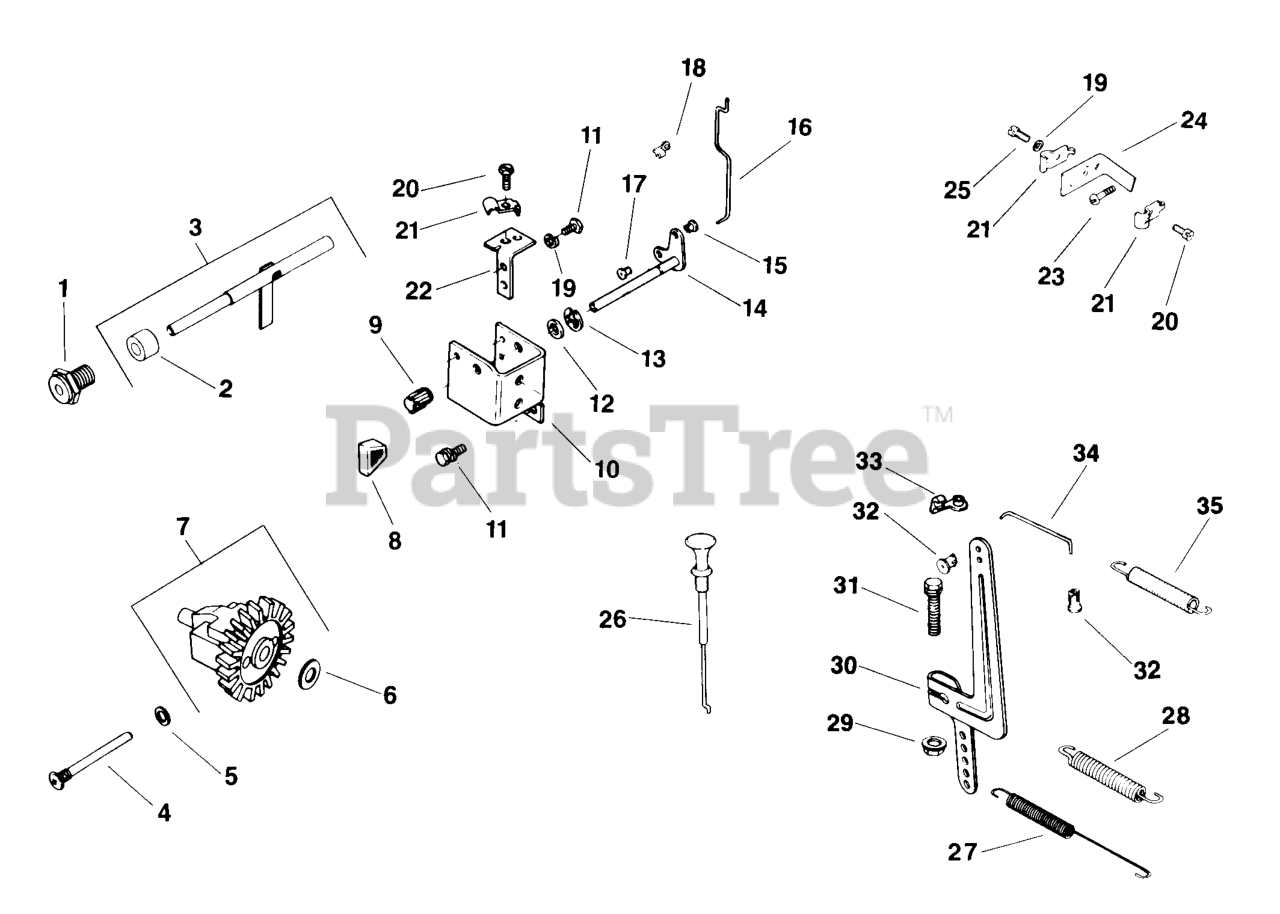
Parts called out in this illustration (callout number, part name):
1	BUSHING
2	SPACER USE 25 112 17-S
3	KIT, SHAFT
7	KIT, GOVERNOR GEAR
17	BUSHING - USE 25 158 09
29	PALNUT, 1/4-20
32	BUSHING - USE 47 158 06
34	LINKAGE - USE 47 079 10
